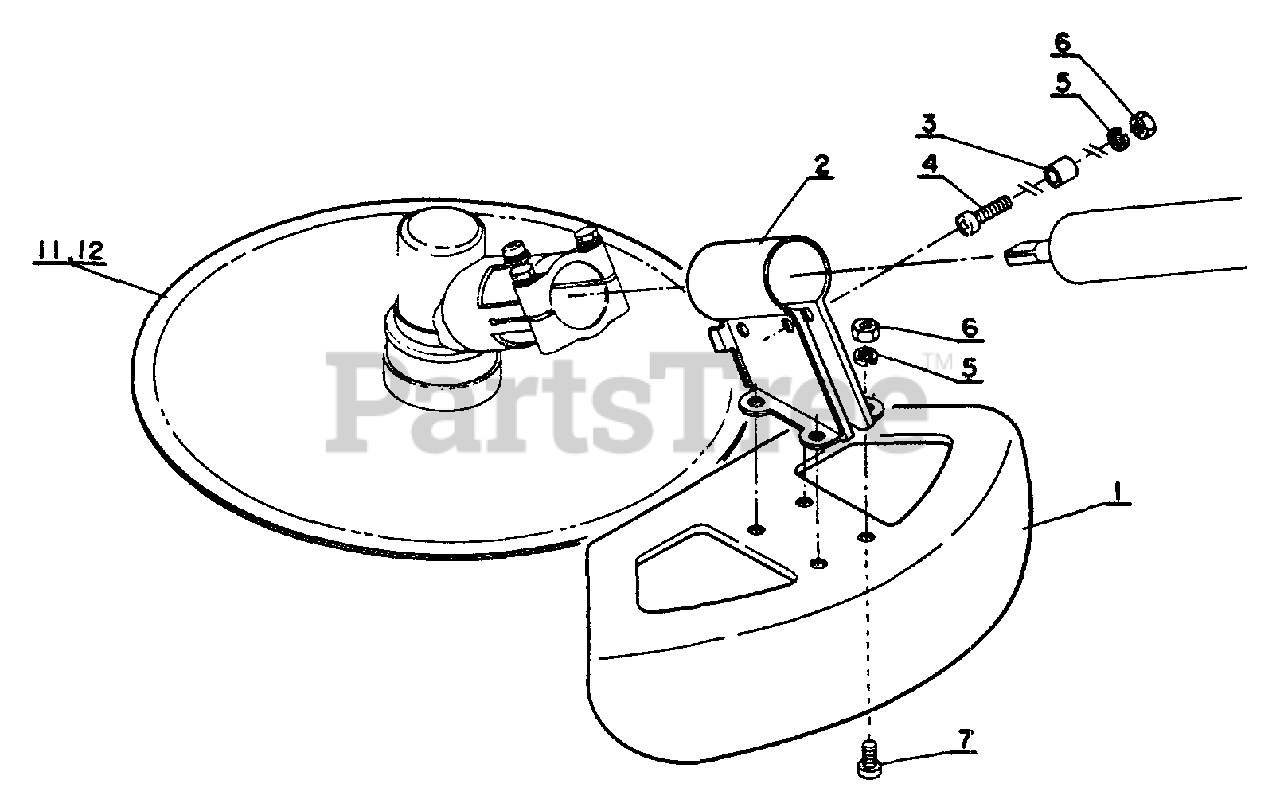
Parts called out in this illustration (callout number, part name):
1	SHIELD, DEBRIS
2	BRACKET, SHIELD
4	SCREW - 5X18
5	LOCKWASHER - 5
7	SCREW - 5X8
11	SAW, CIRCULAR
12	BLADE - 8 TOOTH -- 10" (25cm)
